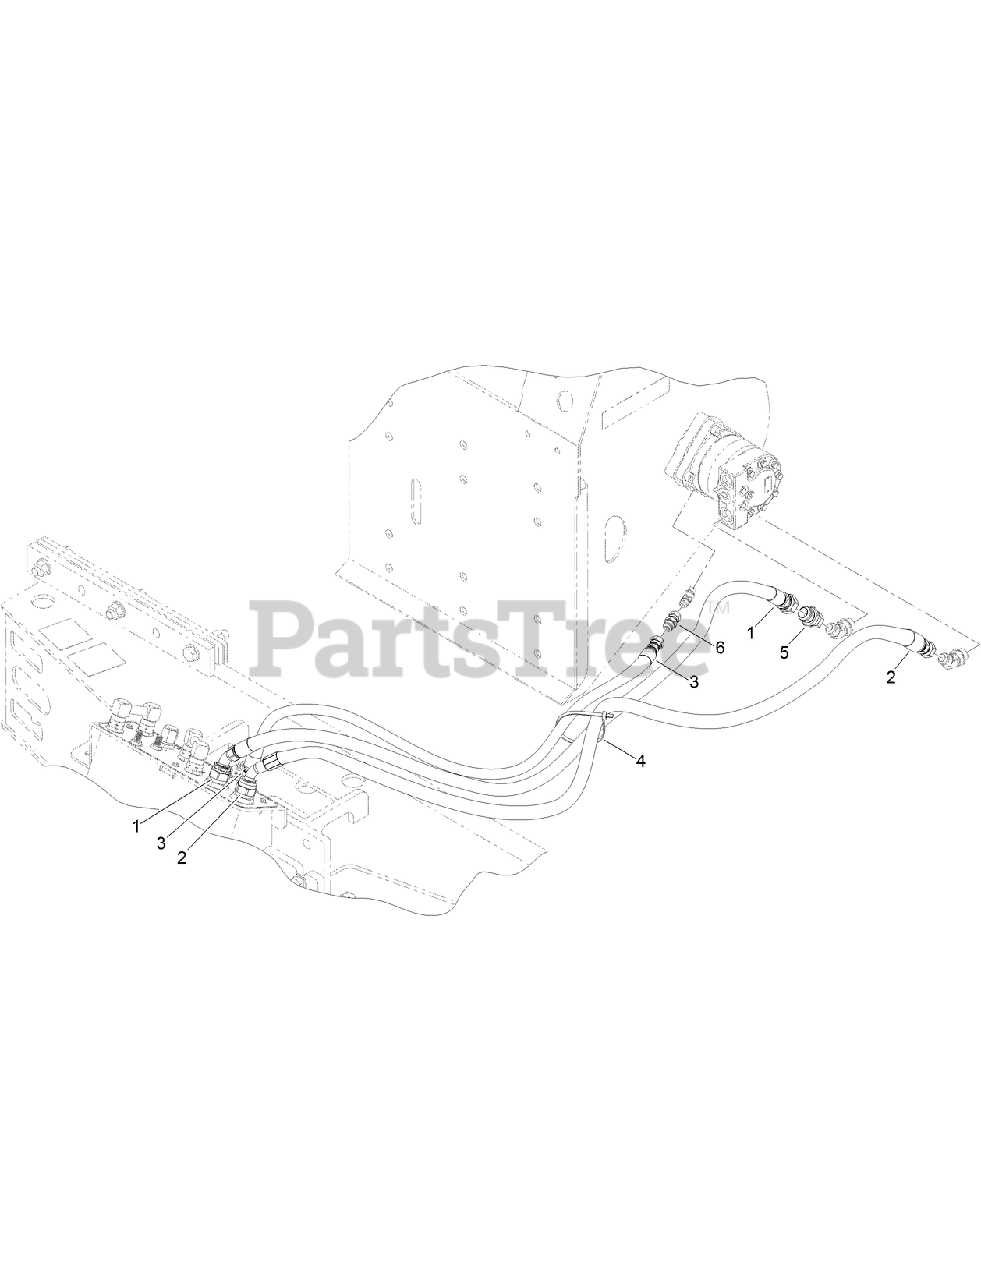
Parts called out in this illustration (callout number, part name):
1	HOSE-HYD
2	HOSE-HYD
3	HOSE-HYD
4	TIE-CABLE
5	ADAPTER-REDUCER
6	ADAPTER-STR
